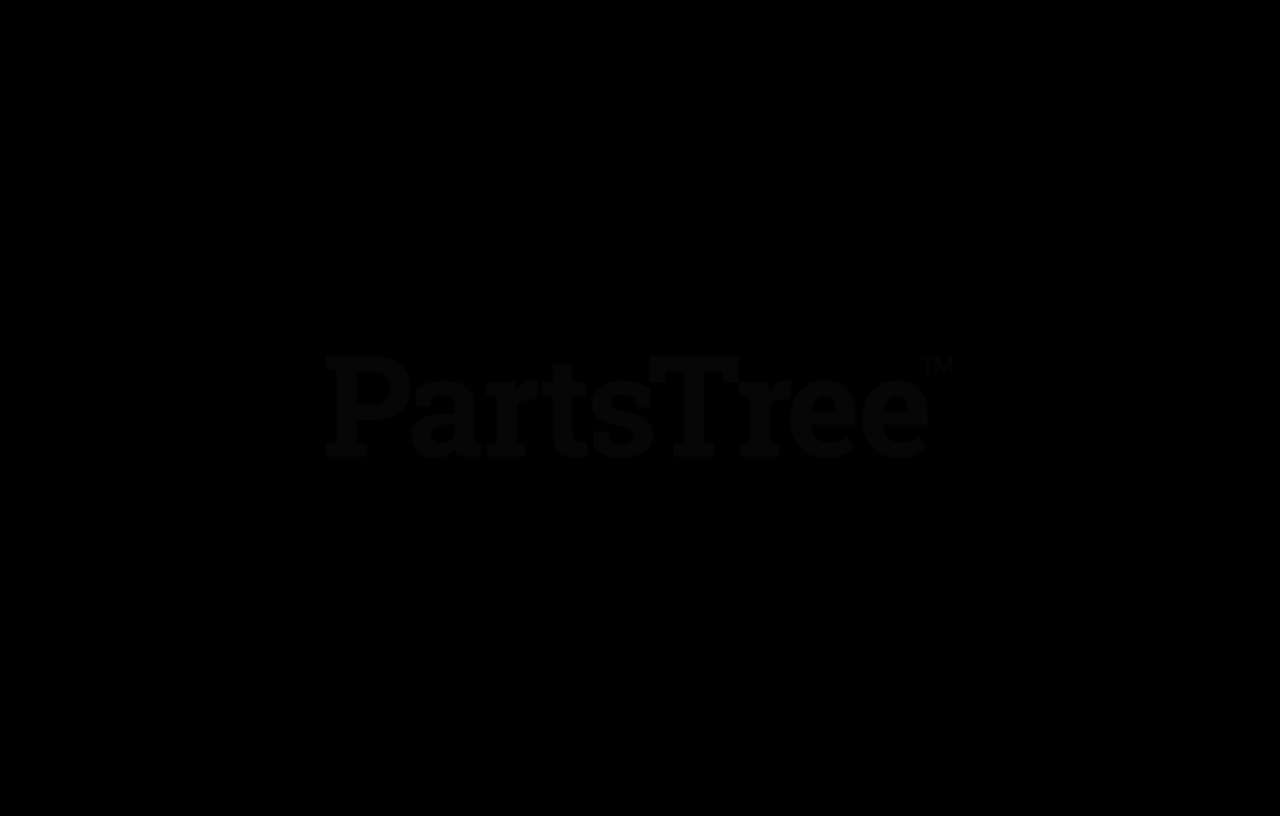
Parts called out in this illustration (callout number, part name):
1	Hose, Hydraulic
2	Hydraulic, Fitting Elbow
4	Hose, Hydraulic
5	Hose, Hydraulic
6	Fitting, Hydraulic
7	Cable Tie
8	Adapter, Face Seal 8 x 8 .50 O-Ring
9	Hose, Hydraulic .50
10	Adapter, Hydraulic Steel .875 to .75
